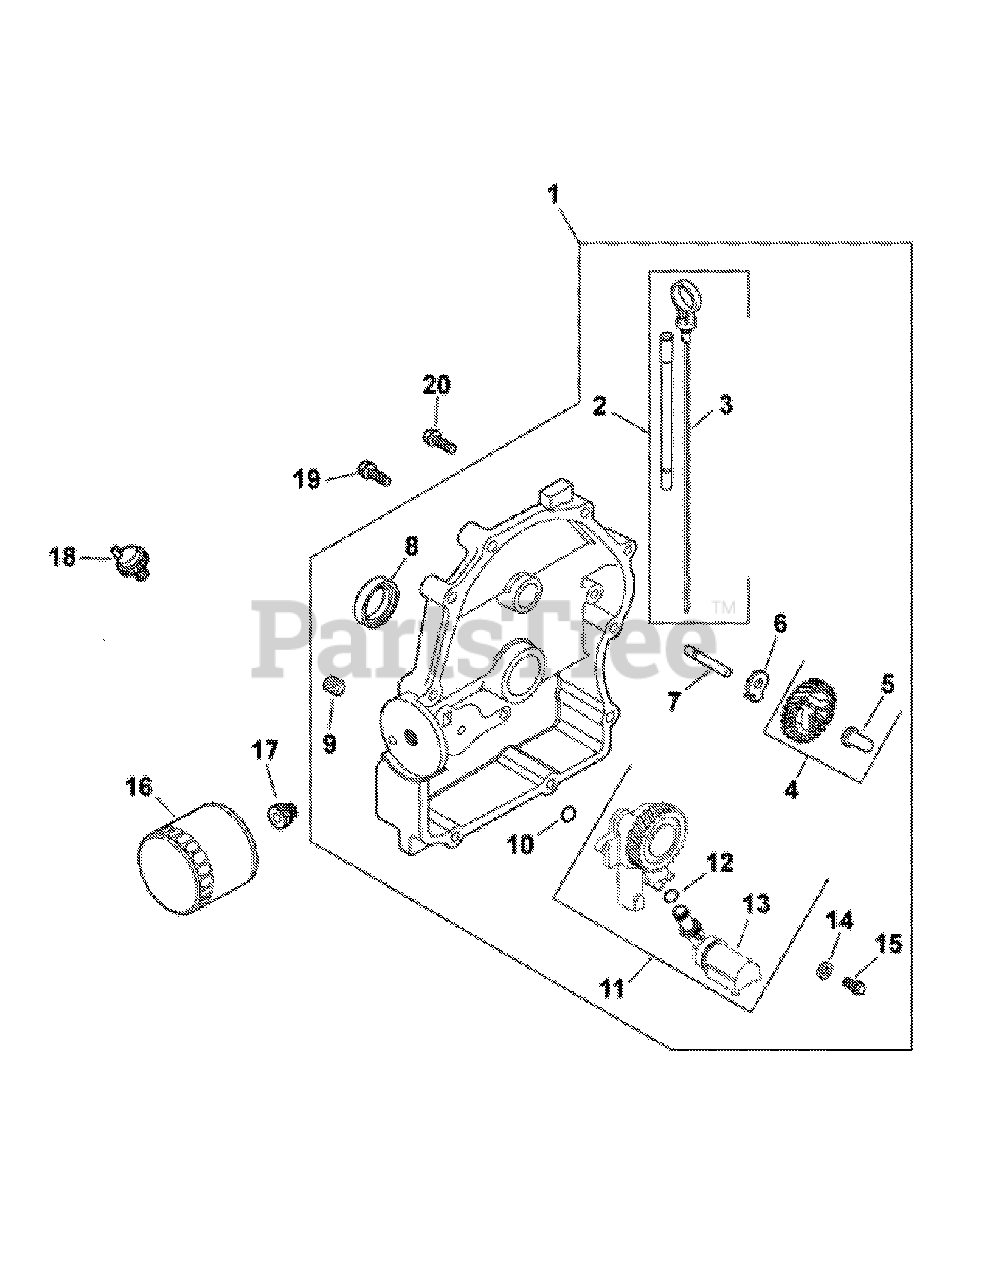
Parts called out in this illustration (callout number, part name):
1	Plate, Closure & Bearing (includes 2-15)
2	Kit, Dipstick & Sipstick Tubes (includes 3)
4	Kit, Governor Hear With Pin (includes 5)
5	Pin, Governor Regulating
7	Shaft, Governor Gear
9	Plug, Ctsk Pip 1/8"
11	Kit, Oil Pump Assembly (includes 12,13)
12	O-Ring, Oil Pick Up
13	Pick Up, Oil
14	Washer, Flat 6mm
15	Screw, Flg Thd Frm M6X1.0X25
17	Nipple, Oil Filter
18	Switch, Oil Pressure
19	Screw, Flg Thd M8X1.25X45
20	Screw, Flg Thd M8X1.25X45
